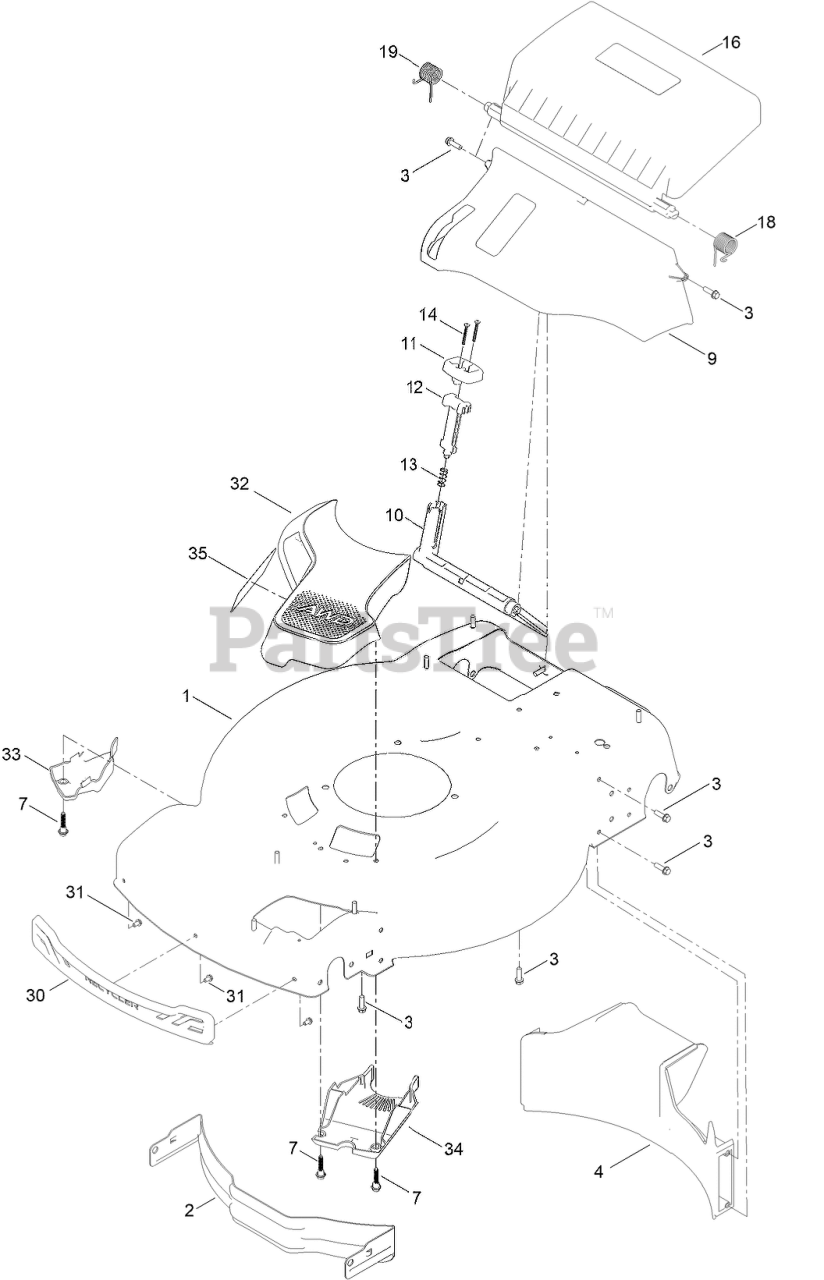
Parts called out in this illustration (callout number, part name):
1	HOUSING ASM
2	BAFFLE-FRONT
3	SCREW-HWH
4	BAFFLE-REAR, RWD
7	SCREW-SHOULDER, HHF
9	ASM-CHUTE, IN MOLD
10	DEFLECTOR-RECYCLE
11	KNOB-RECYCLE
12	LATCH-RECYCLE
13	SPRING-COMPRESSION
14	SCREW-PPH
16	ASM-REAR DOOR, IN MOLD
18	SPRING-TORSION, LH
19	SPRING-TORSION, RH
30	BUMPER-FRONT
31	SCREW-PLASTIC, HWH
32	ASM-INTAKE, AWD
33	COVER-INTAKE, BOTTOM
34	COVER-BELT, LOWER (AWD)
